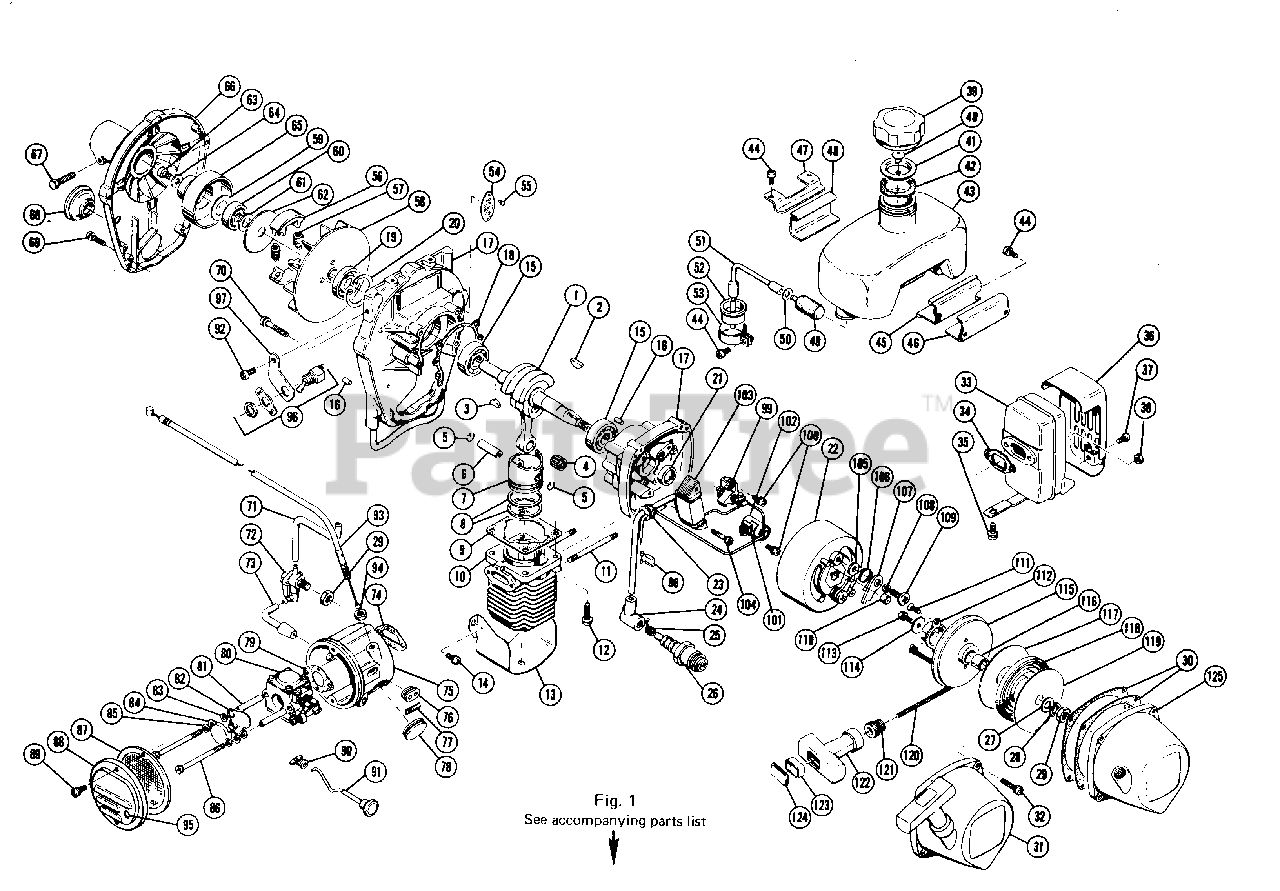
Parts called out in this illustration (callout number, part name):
1	Crankshaft
2	Woodruff key
3	Woodruff key
4	Roller bearing
6	Piston pin
8	Piston ring
9	Cylinder packing
10	Cylinder
11	Stud bolt
13	Cylinder cover
15	Ball bearing
16	Knock pin
17	Crankcase set
18	Crankcase packing
22	Flywheel
23	Rubber bushing
24	Spark plug cap
25	Spark plug connector
26	Spark plug
28	Spring washer
30	Starter case packing
31	Starter ass'y
34	Muffler gasket
34A	Muffler assembly with spark arrestor (Not included as original equipment)
36	Muffler cover
38	Lock nut
39	Fuel tank cap
40	Check valve
41	Check valve holder
42	Fuel tank cap packing
43	Fuel tank
45	Fitting rubber
46	Fuel tank holder
47	Fuel tank holder
48	Rubber seat
49	Fuel strainer
51	Fuel pipe (1)
52	Fuel pipe connector
54	Model plate-not serviced
55	Rivet-not serviced
56	Clutch shoe
57	Clutch spring
58	Cooling fan
60	Ball bearing
61	Clutch spacer
62	Clutch plate
63	H.S.H. bolt
66	Fan cover
68	Spark plug cap cover
71	Fuel pipe (O)
72	Fuel cock
73	Fuel pipe (O-C)
75	Carburetor case
77	Caution label
78	Rubber plug
80	Carburetor ass'y
81	Carburetor spacer
82	Choke shutter
85	Carburetor washer
87	Air filter
88	Air filter cap
90	Rubber bushing
91	Choke rod
93	Throttle cable
95	Carburetor grommet
96	Switch-toggle assembly (includes 97)
97	Plate-switch mounting
98	Terminal switch spade
99	Contact point set
102	Condenser
103	Ignition coil
105	Adjusting washer
106	Dog spring
108	Dog spacer
110	Nylon cap
112	Pawl catcher
115	Recoil drum
117	Side plate
118	Rewind spring
119	Side plate
120	Starter rope
121	Rope guide
122	Starter grip
123	End piece
124	Grip cap
125	Starter case
